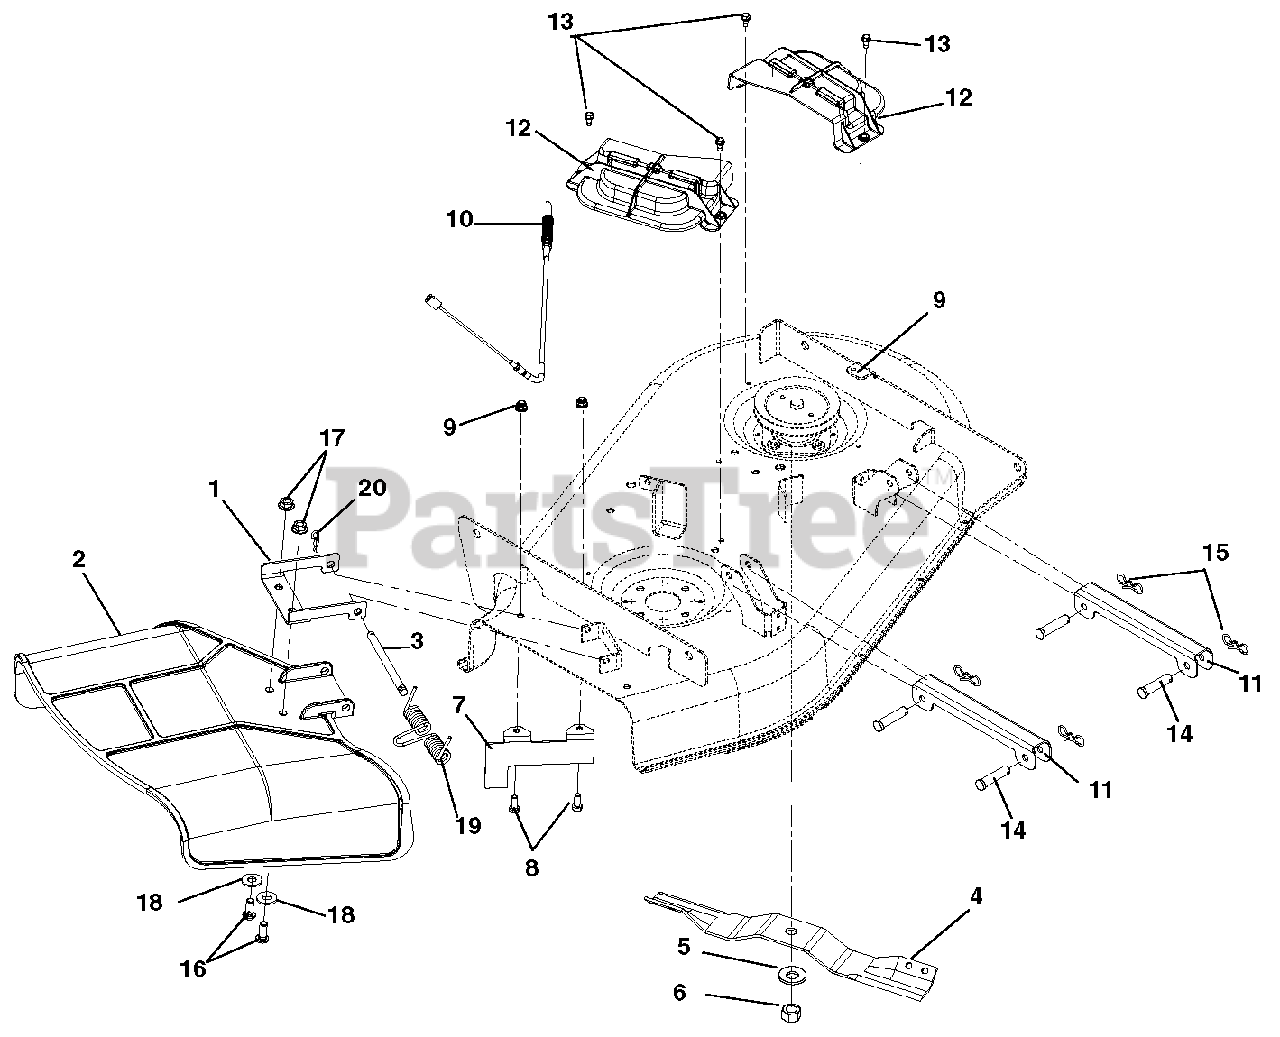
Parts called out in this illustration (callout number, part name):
1	Chute Reinforcement
2	Molded Chute
3	Pin, 5/16 x 3.88"
4	Blade, 17.2" x .156 (SN - 000101 thru 011621)
5	Washer, Beveled .63 x 1.625 x .14
6	Nut, Hex .62-18
7	Bracket, Baffle Discharge 34"
8	Bolt, Hex .31-18 x .75 Grade 5
9	Nut, .31-18 Nyloc Flange
10	Cable, PTO
11	Bracket, Stabilizer Link
12	Cover, Belt Molded
13	Screw, Tapping .25-20 x .50 Hex Washer Head
14	Pin, Clevis .375 x 2.00
15	Pin , Bow Tie Locking
16	Screw, .31-18 x .75
17	Nut, Locking Top Flange .31-18
18	Washer, Flat-Steel .38 x .875 x .083
19	Spring, Torsion
20	Pin, Hair .08 x .18 x 1.18
